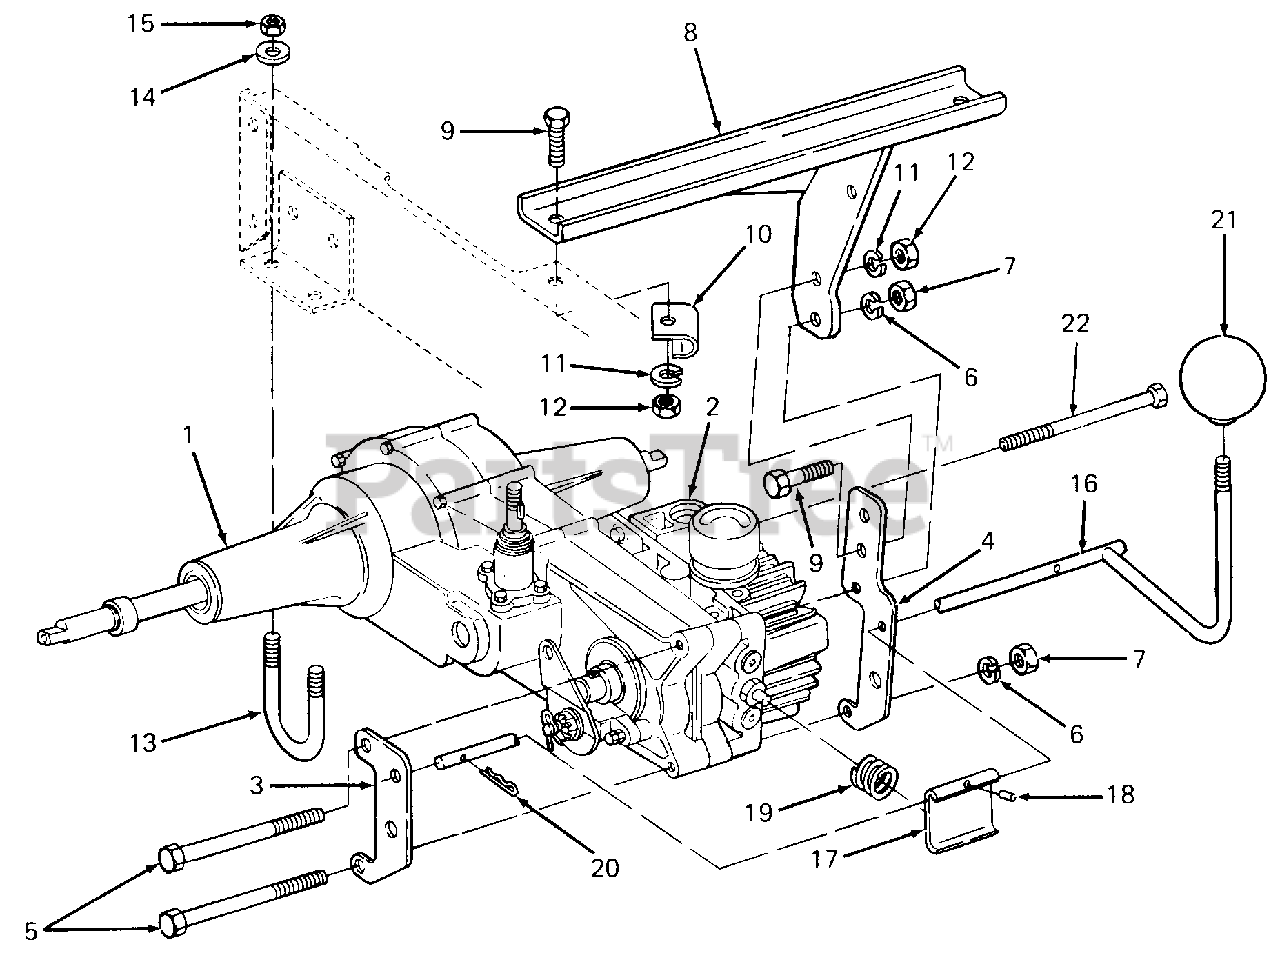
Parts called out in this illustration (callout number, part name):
1	Transaxle
2	Pump, Hydro
3	Bracket, Transmission Dump Valve
4	Bracket, Transmission Dump Valve Torque
5	Screw, Hex Cap, 5/16-18 X 4.5 Lg GR5
6	Washer, Lock, 5/16
7	Nut, Hex, 5/16-18 GR5
10	Clip, Cable
11	Washer, Lock, 3/8
12	Nut, Hex, 3/8-16 GR5
13	U-Bolt, 5/16-18 X 1.75 Lg
14	Washer, Bell, .345 X .88 X .060 Thk
15	Nut, Hex Center Lock, 5/16-18 GR5
16	Rod, Dump Valve
17	Lever, Dump Valve
18	Pin, Spiral Spring, 1/8 Dia X .75 Lg
19	Spring, Compression
20	Pin, Internal Cotter
21	Knob, Ball, 1/4-20 Trd
22	Bolt, Hex Patch, 5/16-18 X 4.5 Lg GR5
